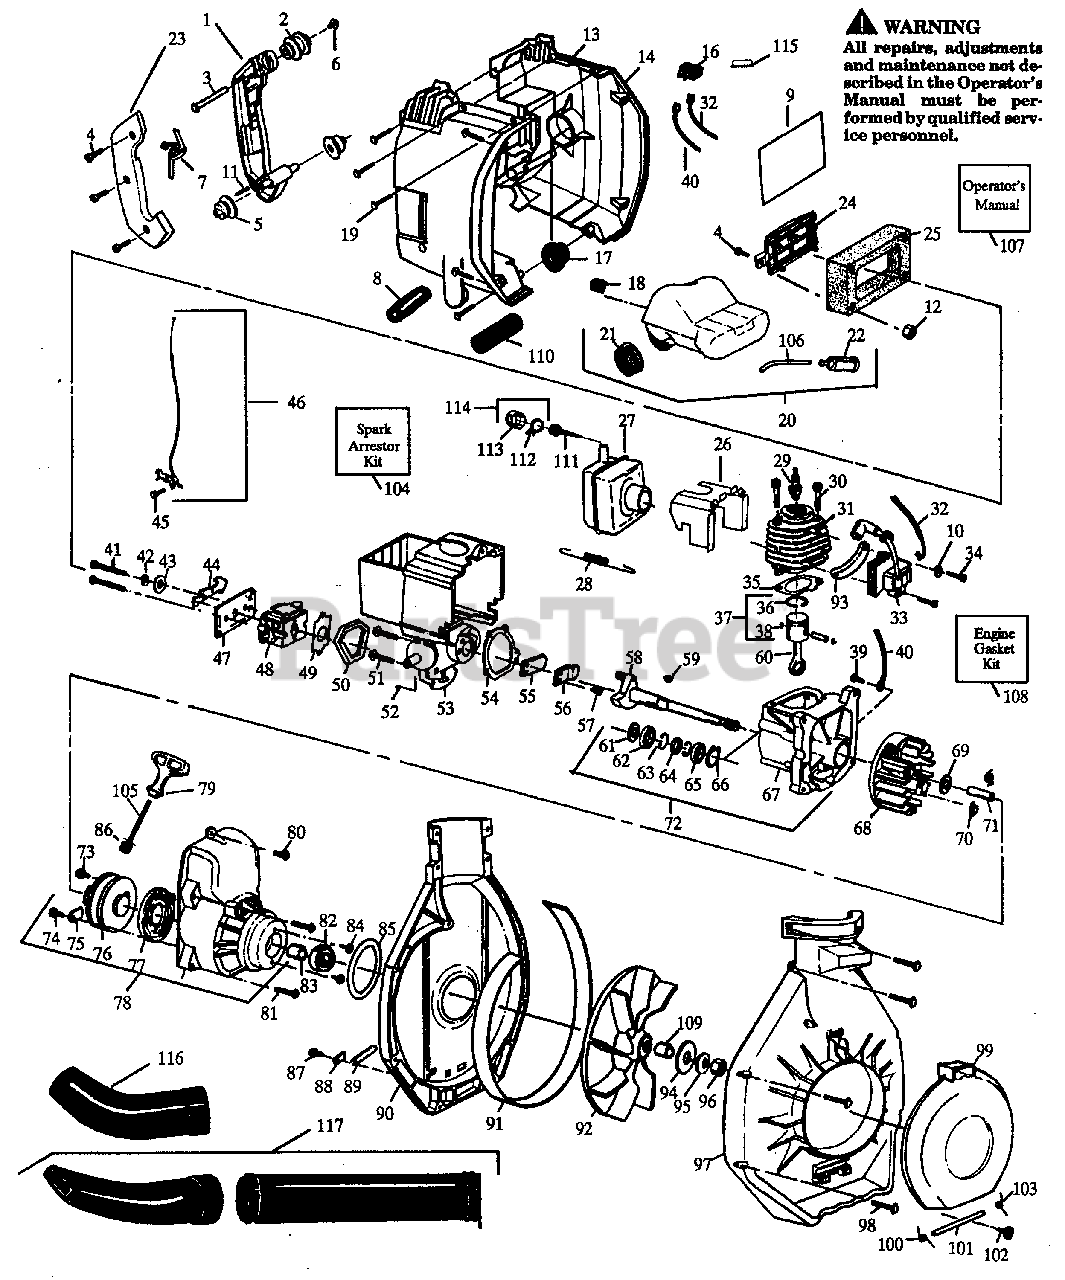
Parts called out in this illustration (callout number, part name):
2	Front Isolator
4	Screw
5	Rear Isolator
8	Assist Handle Tube
9	Instruction Decal
14	Shroud-Right
16	Switch
17	Isolator
18	Isolator
20	Fuel Tank Ass'y.
21	Fuel Cap (w/ retainer)
22	Fuel Pick-up Ass'y.
23	Handle Cover
25	Air Filter
26	Air Baffle
29	Spark Plug (CJ-8Y)
31	Cylinder
32	Lead Wire
33	Ignition Module
35	Gasket
36	Piston Ring
37	Piston Kit
38	Retainer
40	Ground Wire
42	Wave Washer
44	Choke Shutter
46	Cable Assembly
48	WT-141 - Type 1 & 2
48	WT-141A - Type 3
52	Ground Wire
53	Reed Block
55	Reed Valve
56	Reed Stop
58	Crankshaft-See Service Ref. 3
60	Piston Rod
62	Inner Bearing
63	Retaining Ring
64	Crankshaft Seal
65	Outer Bearing
66	Retaining Ring
67	Crankcase
68	Flywheel
69	Washer
72	Crankcase/CrankshaftAssy.
75	Retainer
77	Starter Spring
78	Fan Housing Kit
79	Starter Handle
82	Bearing
84	Screw
85	"O" Ring
88	Retainer
89	Roll Pin
90	Blower Housing (Upper)
92	Impeller
97	Blower Housing (Lower)
98	Screw
99	Door
105	Rope Kit
106	Line Kit
107	Operators Manual - Type 3
108	Gasket Kit
109	Hub
110	Foam Grip
111	Spark Arrestor Screen
112	Spark Arrestor Clamp
113	Exhaust Deflector Ass'y.
114	Deflector & Clamp Ass'y.
115	Switch Cover-See Service Ref.2
116	Blower Concentrator
117	Tube and Nozzle Ass'y
